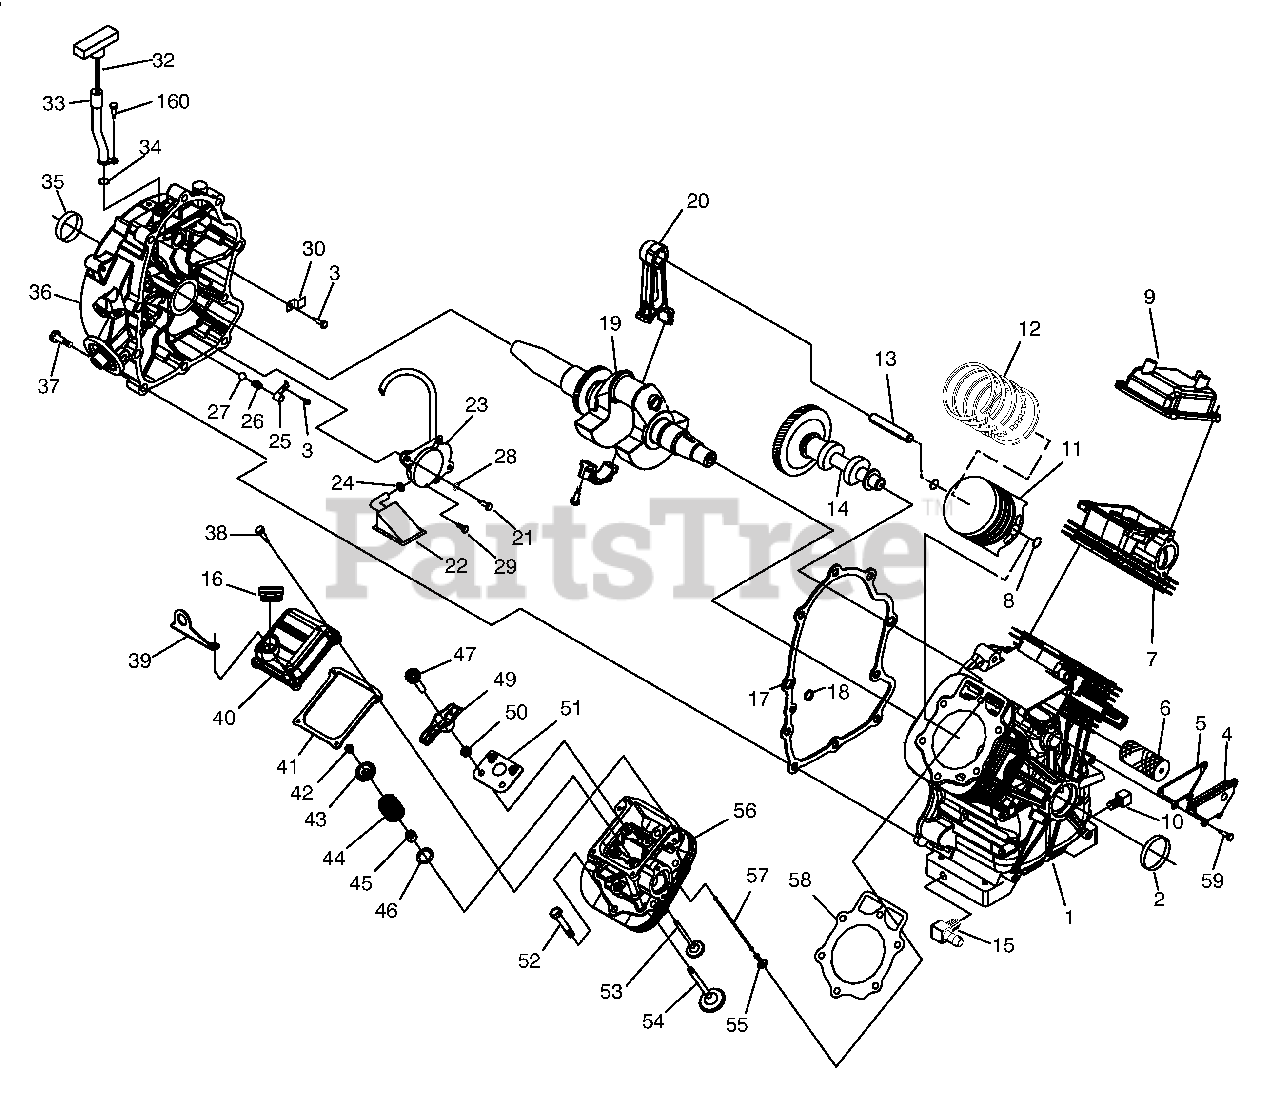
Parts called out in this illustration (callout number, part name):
1	ASSY, CRANKCASE WITH SLEEVE
2	SEAL, 38 I.D. CRANKSHAFT
3	SCREW, HHFCS M6-1.0 X 12 G8.8
4	ASSEMBLY, BREATHER
5	GASKET, BREATHER COVER
6	SEPARATOR, OIL BREATHER
7	ASSEMBLY, HEAD #1
8	RETAINER, PISTON PIN 20
9	ASSY, ROCKER COVER W/BARB
10	PLUG,STD PIPE 3/8" STEEL SQ HEAD
11	PISTON, LC (GT-990)
12	SET, PISTON RING 90MM
13	PIN PISTON
14	ASSEMBLY, CAMSHAFT & GEAR
15	BARBED ELBOW, 90 DEG. 3/8NPT X 3/8 VS
16	ASSEMBLY, OIL FILL CAP
17	GASKET, CRANK CASE
18	SEAL, OIL PASSAGE
19	ASSY, GTH-990 DIRECT DRIVE
20	ASSEMBLY, CONNECTING ROD GT-990
21	SCREW SHC M6-1.0 X 50 G8.8
22	SCREEN, OIL PICKUP
23	ASSY,OIL PUMP GTH W/O O-RING
24	O-RING, 0.49 ID X 0.07 THICK
25	COVER, OIL RELIEF
26	SPRING, OIL RELIEF
27	BALL, 1/2D OIL RELIEF
28	WASHER, LOCK RIB M6
29	SCREW, PLASTITE HI-LOW #10
30	CLAMP, OIL TUBE
32	ASSEMBLY, DIPSTICK GTH-990 PORTABLE
33	TUBE, DIPSTICK
34	O-RING, 3/8 X 1/2
35	SEAL, 42 I.D. CRANKSHAFT
36	GEARCOVER / ADAPTOR GTH990/760
37	SCREW, HHFC M10-1.5 X 55
38	SCREW HHFC M6-1.0 X 25
39	LIFT HOOK, GT990/760
40	COVER, ROCKER W/OIL FILL "GENERAC" TEXT
41	GASKET, VALVE COVER
42	KEEPER, VALVE SPRING
43	RETAINER, VALVE SPRING
44	SPRING, VALVE
45	SEAL, VALVE STEM D7
46	WASHER, VALVE SPRING
47	STUD, ROCKER ARM PIVOT
49	ROCKER ARM
50	NUT, HEX M8-1.0 GB YELLOW CHROM
51	PLATE, PUSH ROD GUIDE
52	SCREW HHFC M8-1.25 X 65
53	VALVE, EXHAUST
54	VALVE, INTAKE
55	TAPPET, SOLID
56	ASSEMBLY, HEAD #2
57	PUSHROD 147
58	GASKET, HEAD
59	SCREW, HHFC M6-1.- X 10mm
60	KIT GEAR COVER
61	KIT GASKET
62	KIT PISTON & RINGS
63	KIT BREATHER ASSEMBLY
64	KIT HEAD ASSEMBLY CYLINDER 1
65	KIT HEAD ASSEMBLY CYLINDER 2
66	KIT OIL RELIEF
